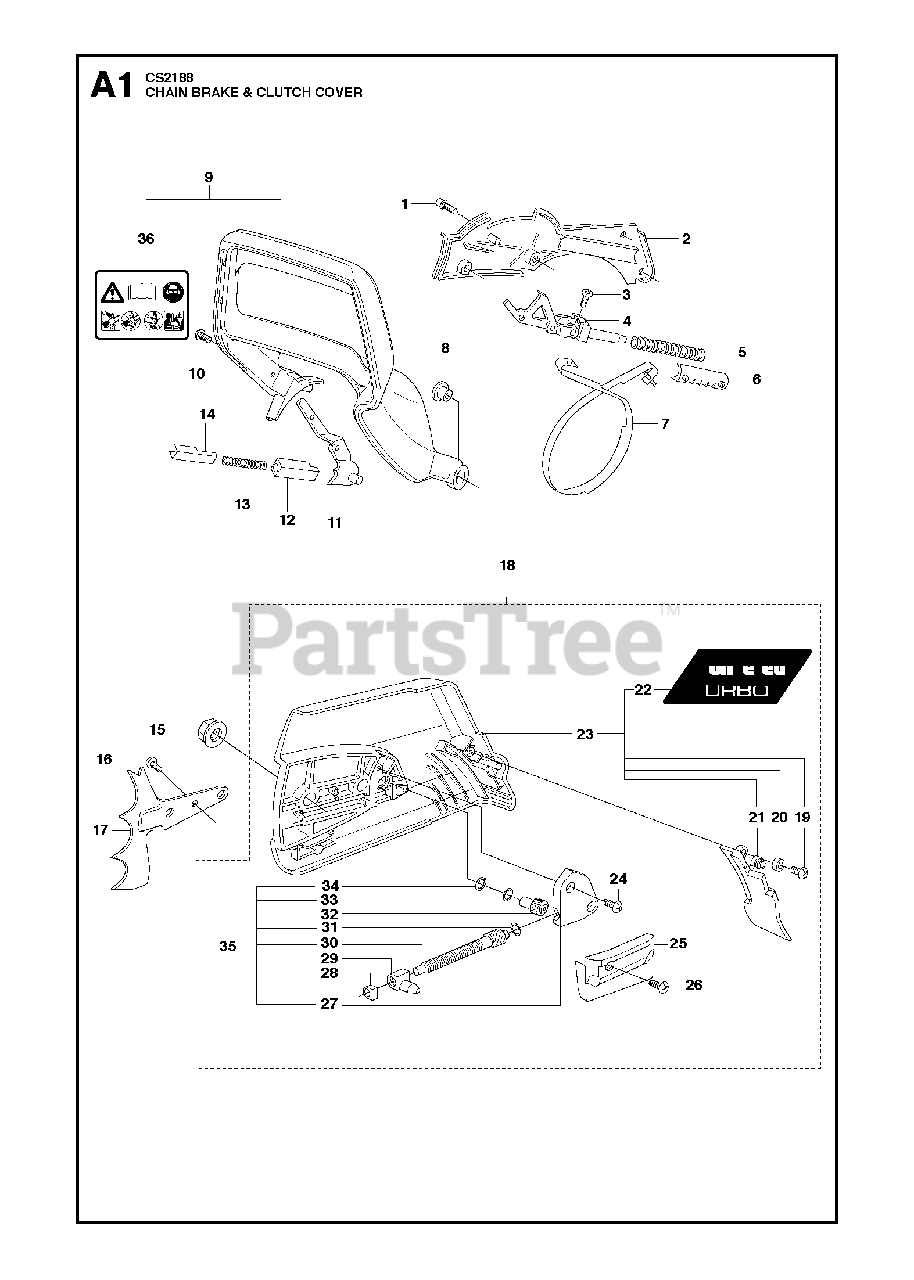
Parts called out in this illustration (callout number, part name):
1	SCREW
4	KNEE JOINT
5	BRAKE SPRING
6	%SUPPORT
7	BRAKE BAND
9	CHAIN BRAKE ASSY
11	BRAKE LEVER
13	LOCK SPRING
14	PROTECTOR
15	NUT M8 FLANGE
17	FELLING DOG
18	CLUTCH COVER
19	SCREW
20	WASHER
21	PROTECTOR
22	DECAL
23	CLUTCH COVER
24	SCREW
25	GUIDE
26	SCREW
27	COVER
28	SLEEVE
29	COUPLING
30	WORM SCREW / ADJUSTER
31	WASHER
32	SCREW
33	WASHER
34	O-RING
35	KIT-CHAIN TENSIONER
36	DECAL
